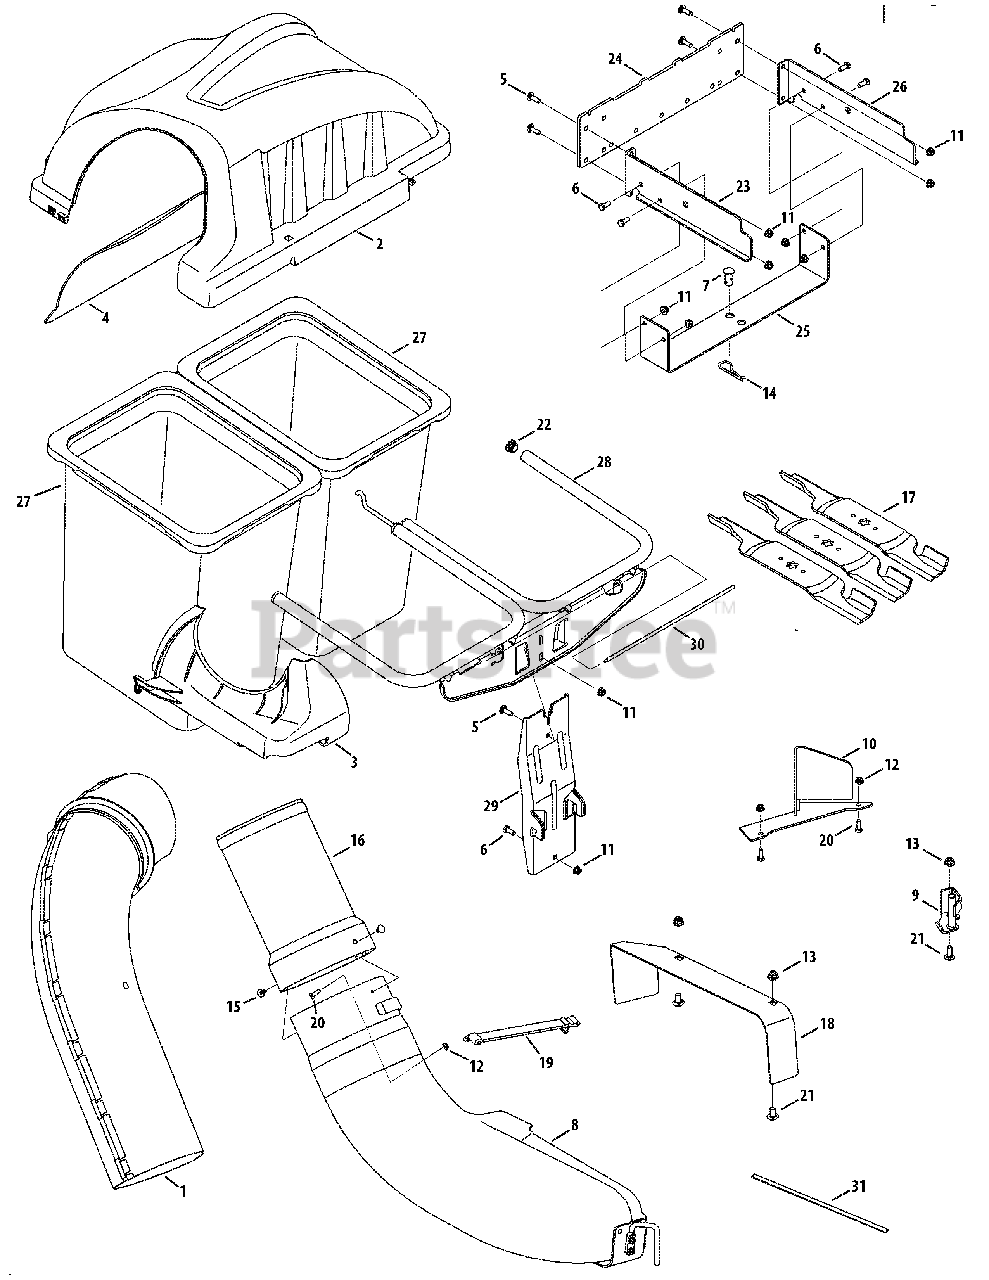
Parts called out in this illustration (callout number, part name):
1	Upper Chute Assembly
2	Double Bagger Cover Assembly
3	Upper Chute Support
4	Bagger Cover Screen
5	Carriage Screw, 5/16-18 x 1.00"
6	Hex Head Screw, 5/16-18 x .75"
7	Clevis Pin, .62" Dia.
8	Bagger Discharge Chute, Elbow
9	Chute Stop Bracket
11	Flange Lock Nut, 5/16-18
12	Flange Lock Nut, 1/4-20
13	Flange Lock Nut, 3/8-16
14	Internal Cotter Pin, .148 x 3.00
15	Ratchet Clip
16	Bagger Chute Adapter
17	Blade, 17.9 Lg. Star Mount
18	Chute Discharge Plate
19	Chute Strap
20	Hex Head Screw, 1/4-20 x .75
21	Carriage Bolt, 3/8-16 x 1.00
23	Mounting Bracket, RH
24	Universal Mounting Bracket
25	Universal Bracket Support, I-Series
26	Mounting Bracket, LH
27	Grass-bag Assembly
30	Cover Hinge Pin
31	Adhesive Strip
